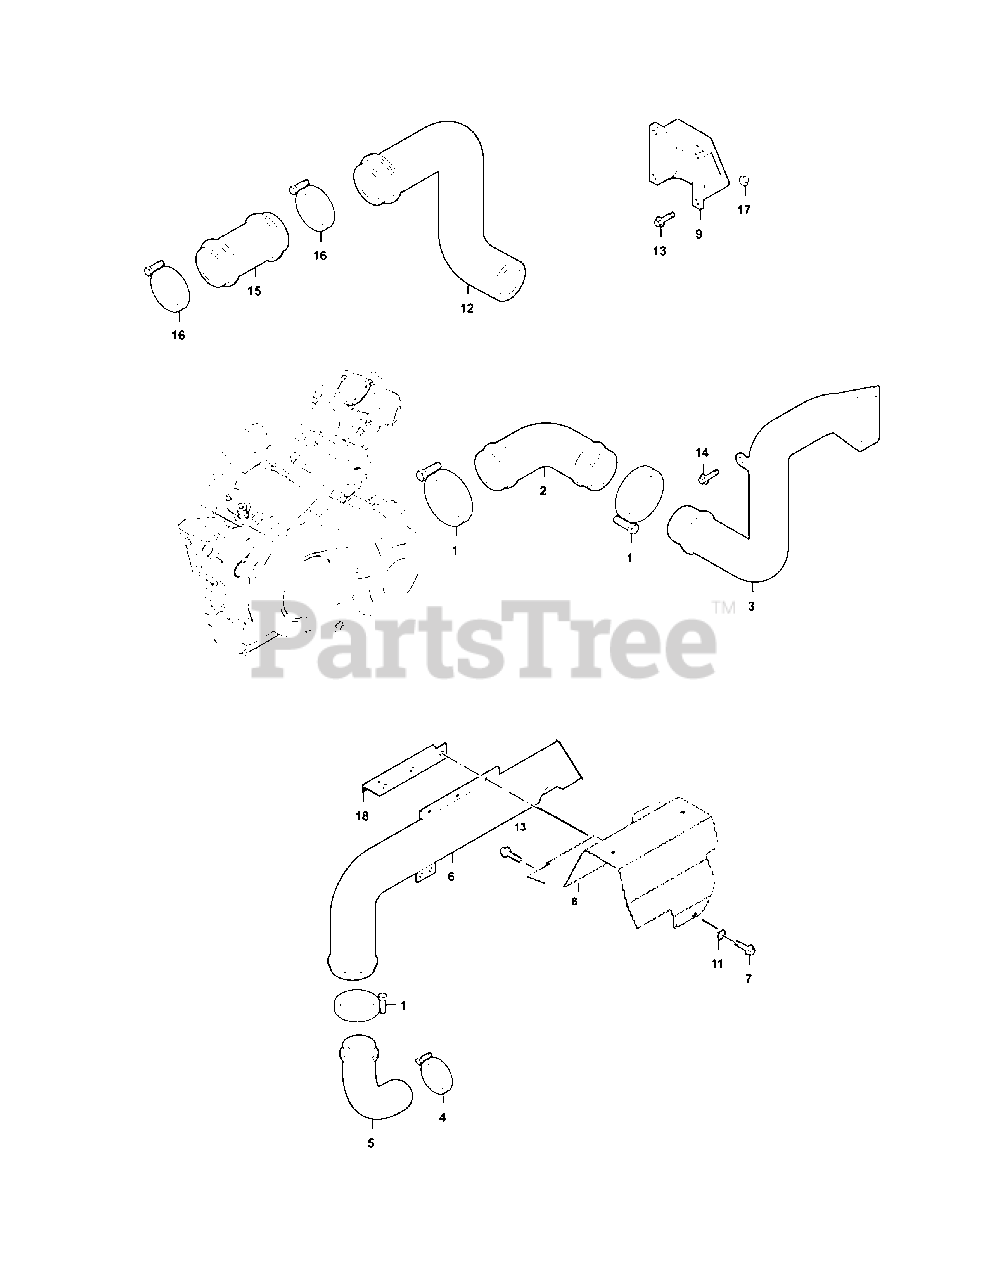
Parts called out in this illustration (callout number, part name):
1	Clamp 250
2	Inlet Pipe Joint, Clutch
3	Inlet Pipe, Clutch
4	Clamp 240
5	Inlet Pipe Joint, Clutch
6	Air-Out Pipe,Clutch
7	Hexagon Flange Bolt M6×16
8	Engine Heat shield I
9	Air-In Pipe Dustproof Cover, Clutch
10	Expansion Bolt(Plastic)
11	Washer6×18×1.6
12	Air-Out Pipe, Fan
13	Hexagon Flange Bolt M6×30
14	Cross large plate head screw M6×16
15	Air-Out Joint, Fan
16	Clamp
17	Hexagon Flange Nut M6
18	Air-Out Pipe Mounting Board,Clutch
